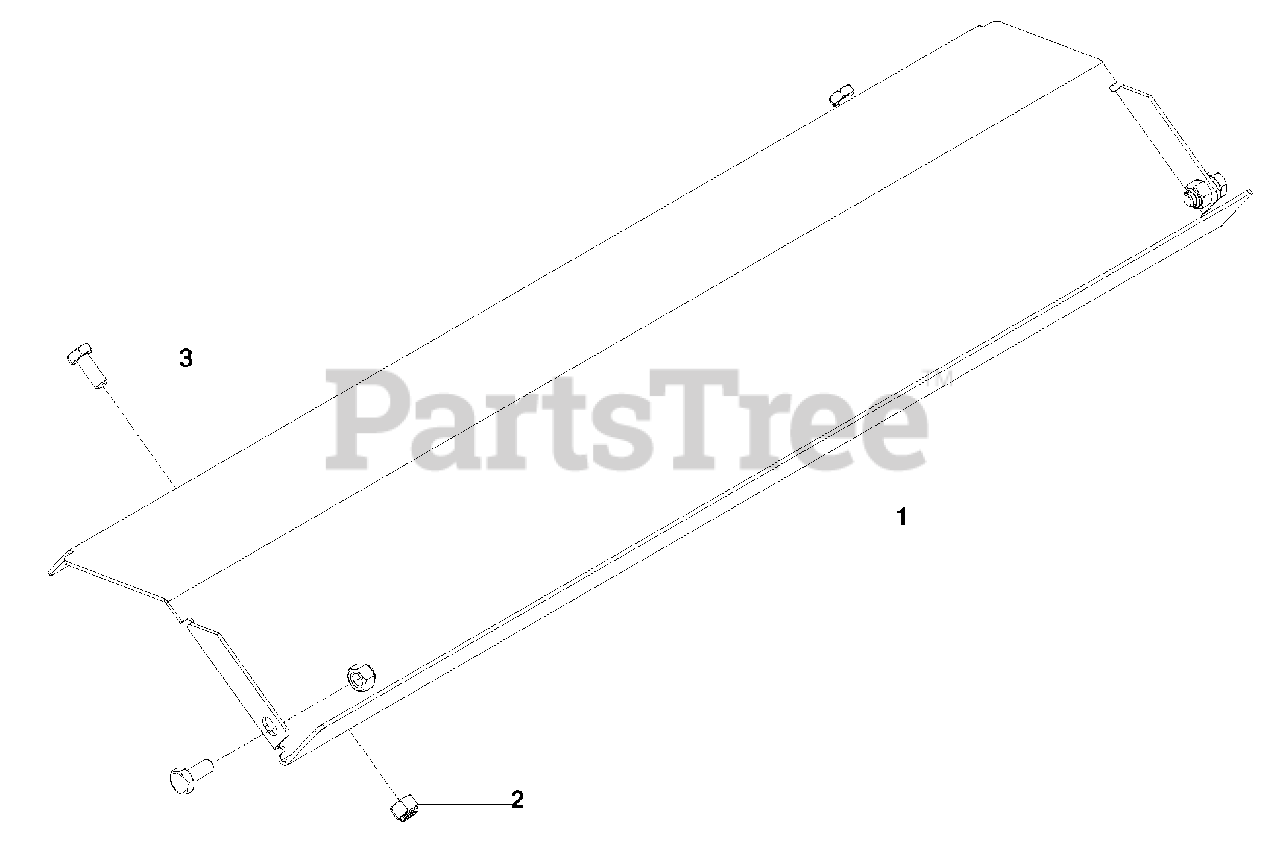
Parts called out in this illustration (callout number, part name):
1	REAR COVER, ORG
2	NUT 1/4-20, NYLOC
3	HCS 1/4-20 X 5/8
